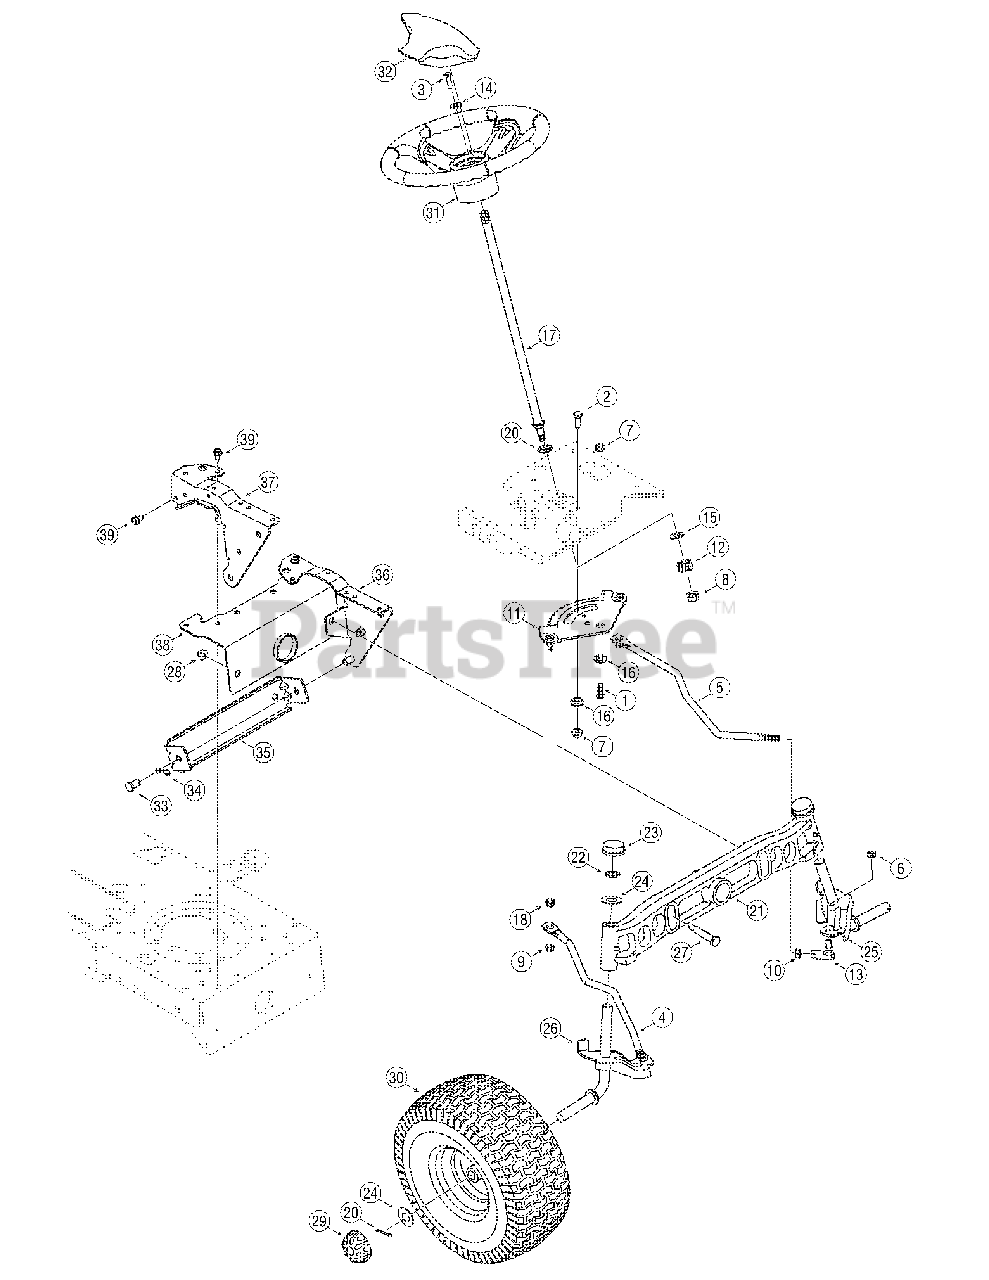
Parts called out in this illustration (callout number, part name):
1	Hex Screw, 3/8-16, 1.00, Gr5
2	Hex Screw, 3/8-16, 1.00, Gr5
3	Hex Screw, 5/16-18, 1.00, Gr5
4	Link, Drag, RH
5	Link, Drag, LH
6	Nut, Hex Lock, 3/8-24
7	Nut, Flange Lock, 3/8-16, Grf, Top Lock
8	Nut, Flange Lock, 7/16-20, Grb, Lock
9	Nut, Flange Lock, 5/16-18, Gr5, SD Lock
10	Nut, Jam 7/16-20, GR2
11	Steering Gear
12	Steering Pinion Gear
13	Ball Joint 7/16-20: Lock
14	Flat Washer.406 x.875 x.105
15	Flat Washer.51 x 1.12 x.06
16	Shoulder Spacer.38 x 1 x.31
17	Steering Shaft
18	Plastic Bushing
19	Hex Flange Bearing
20	Cotter Pin 5/32 x 1.25
21	Cast Iron Pivot Axle
24	Flat Washer.78 x 1.59 x.060
25	Axle Assembly LH
26	Axle Assembly RH
27	Shoulder Screw.50 x 2.230 x 3/8-16
28	Nut, Flange Lock, 3/18-16: Grf Nylon
29	Hub Cap
30	Flange Bearing
30	Flange Bearing w/ Grease Fitting
31	Steering Wheel
32	Steering Wheel Cover
33	Clevis Pin.50 x.78
34	Internal Cotter Pin.080 x 1.5625
39	Screw LD 5/16-18 x.75
